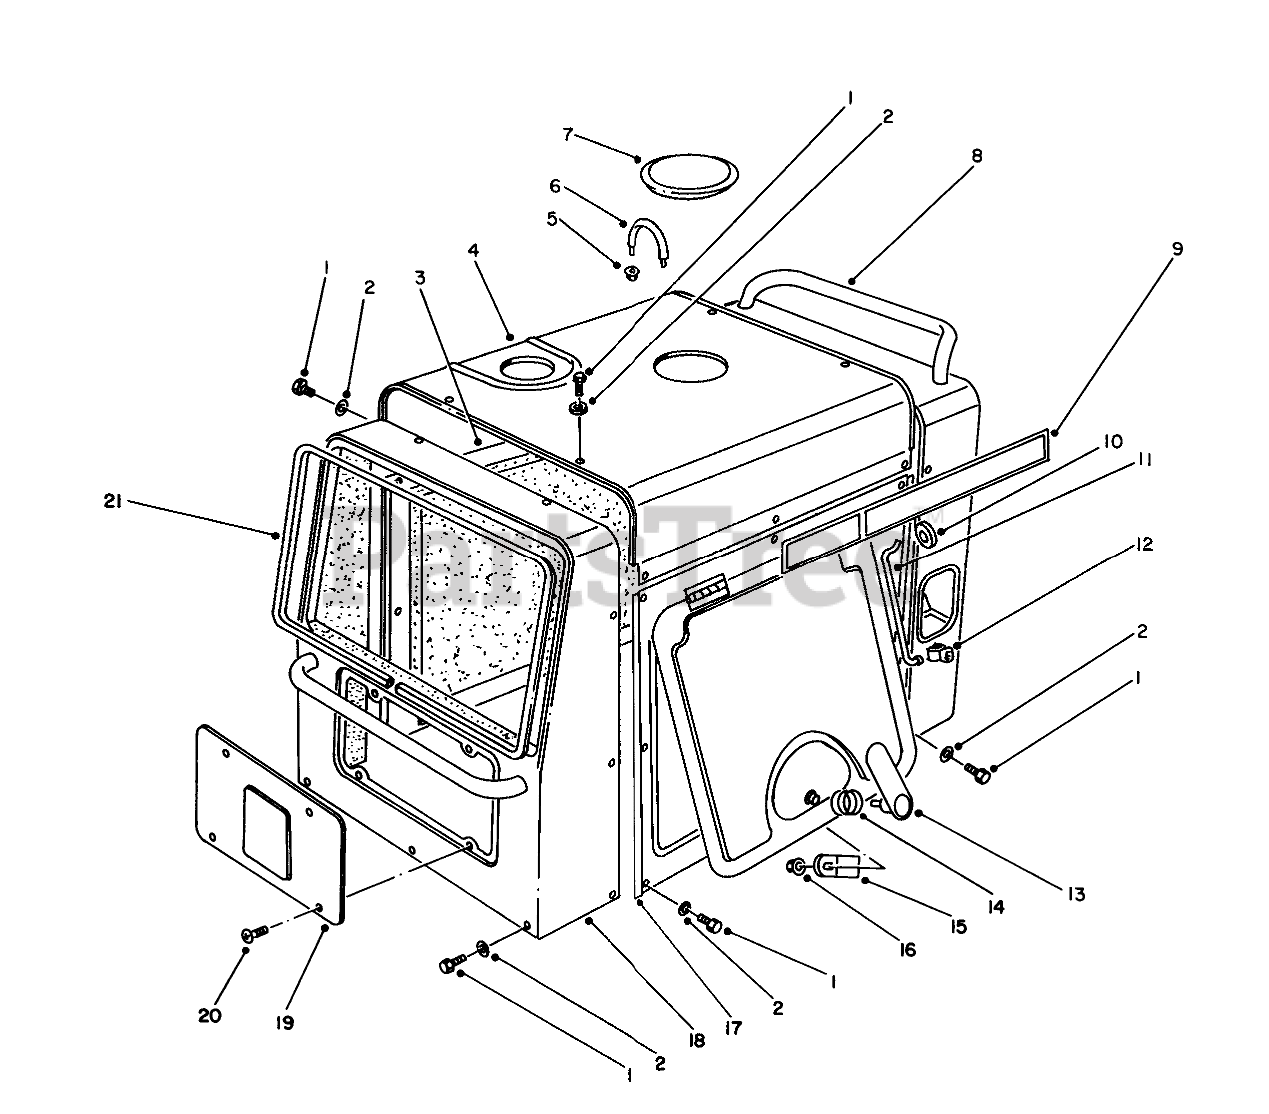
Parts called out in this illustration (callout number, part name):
2	Washer
3	Cover L.H.
4	Cover-Upper
6	U-Bolt
8	Cover-Rear
9	Decal-Toro
10	Grommet
11	Rod-Door Stop
12	Clamp
13	Handle-Door
14	Spring
15	Plate-Handle
17	Cover R.H.
18	Cover-Front
19	Lid-Terminal
20	Screw
21	Seal-Front Cover
